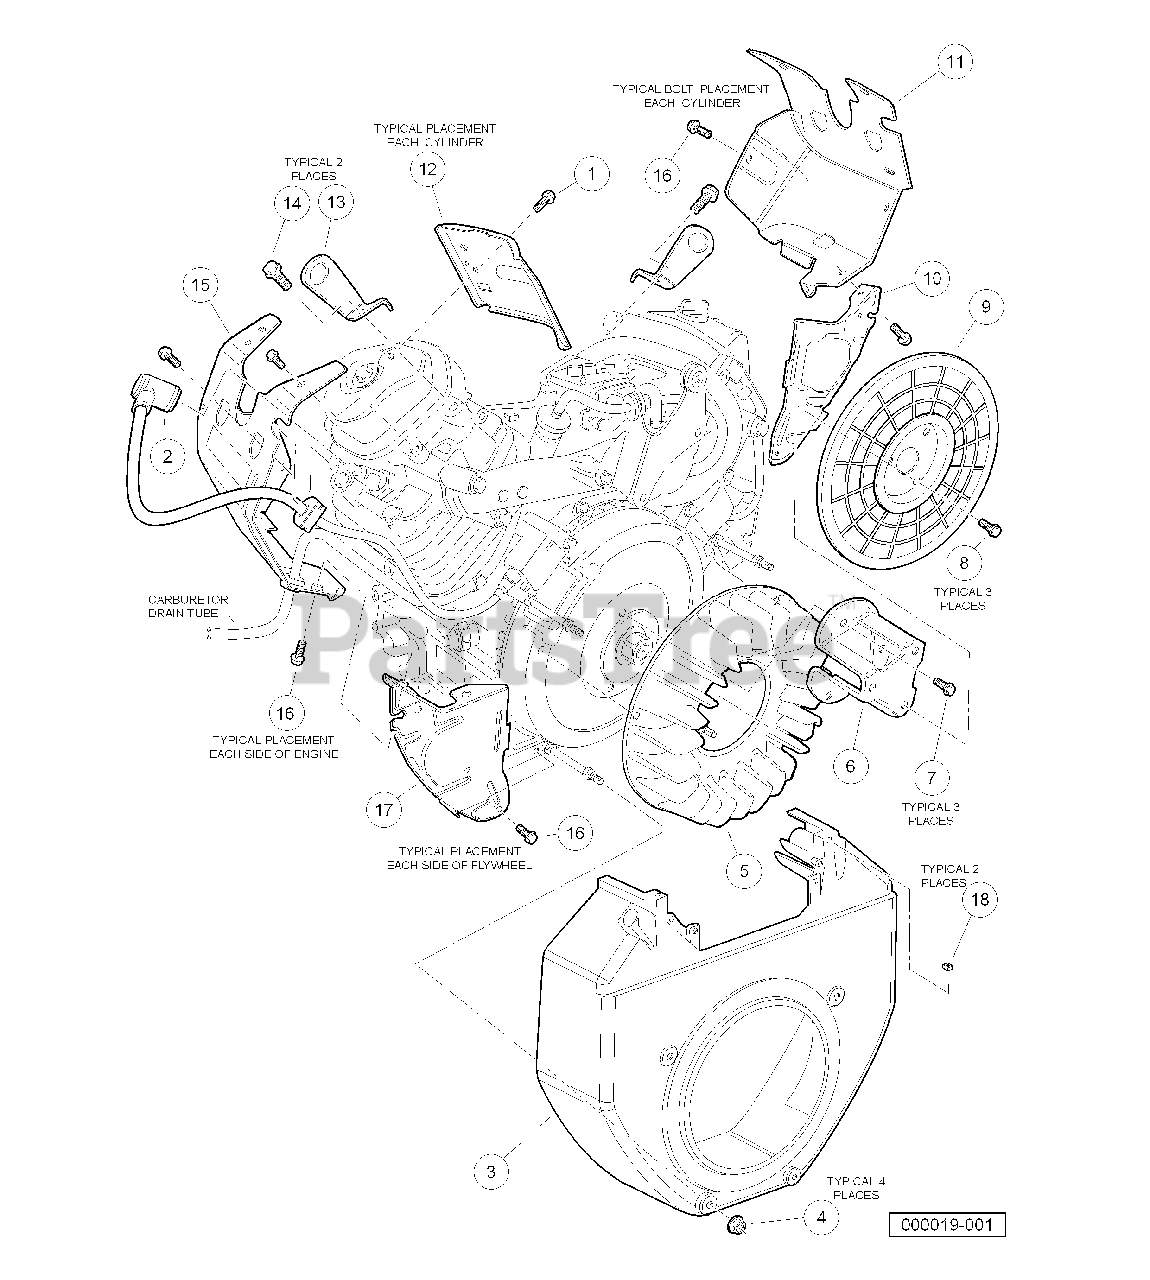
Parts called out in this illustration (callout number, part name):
1	Bolt, Flange Head, M6 X 11 X 4
2	Cap Assy, Noise Suppressor
3	Cover, Fan, Bright Red
4	Nut, Flange, M6
5	Fan, Cooling
6	Holder, Screen Grid
7	Bolt, Flange Head, M8 X 1.25 X 16
8	Bolt, Flange Head, M6 X 1 X 12
9	Grid Screen, PTO
10	Plate, R Side
12	Shroud, Head
13	Hanger, Engine
14	Bolt, Flange Head, M8 X 1.25 X 20
16	Bolt, Flange Head, M6 X 1 X 12
17	Plate, Left Side
18	Nut, Square, 5mm
